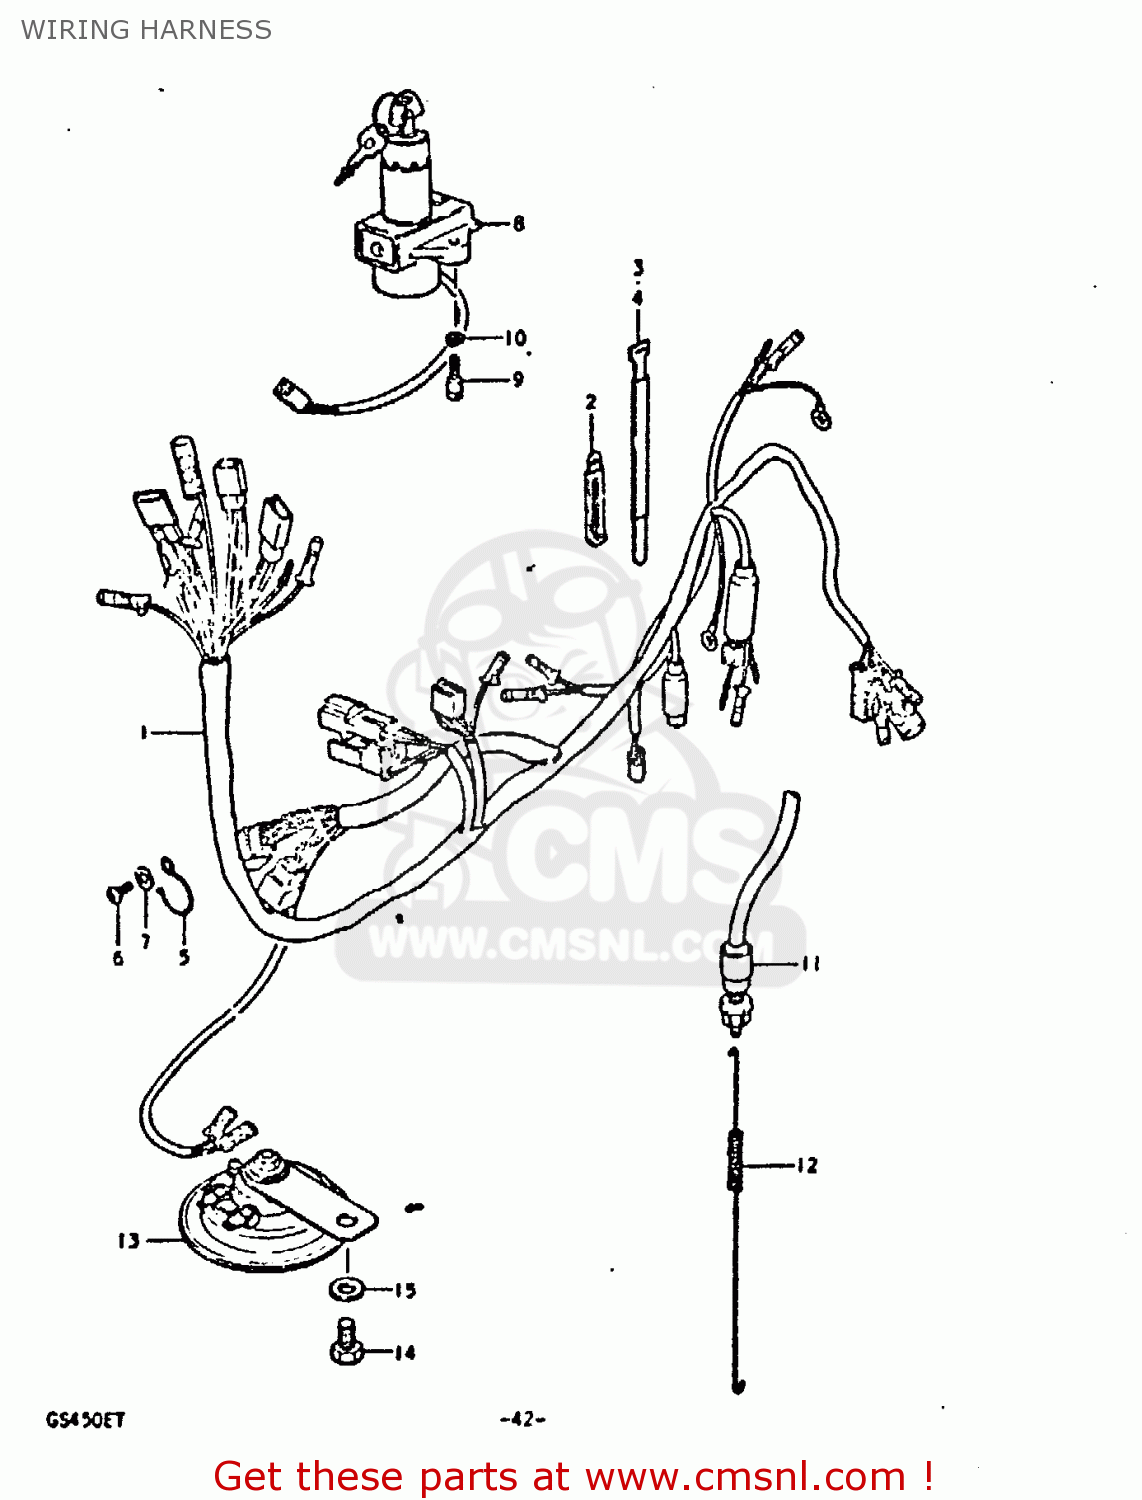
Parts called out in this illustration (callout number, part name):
1	WIRING HARNESS
2	CLAMP
3	CLAMP
4	CLAMP
5	GUIDE,WIRING HARNESS
6	SCREW 6X12
7	WASHER 6MM
8	LOCK ASSEMBLY,STEERING
9	BOLT
10	LOCK WASHER
11	SWITCH ASSEMBLY,STOP LAMP
12	SPRING
13	HORN ASSEMBLY,LOW PITCH
14	BOLT 8X12
15	WASHER
